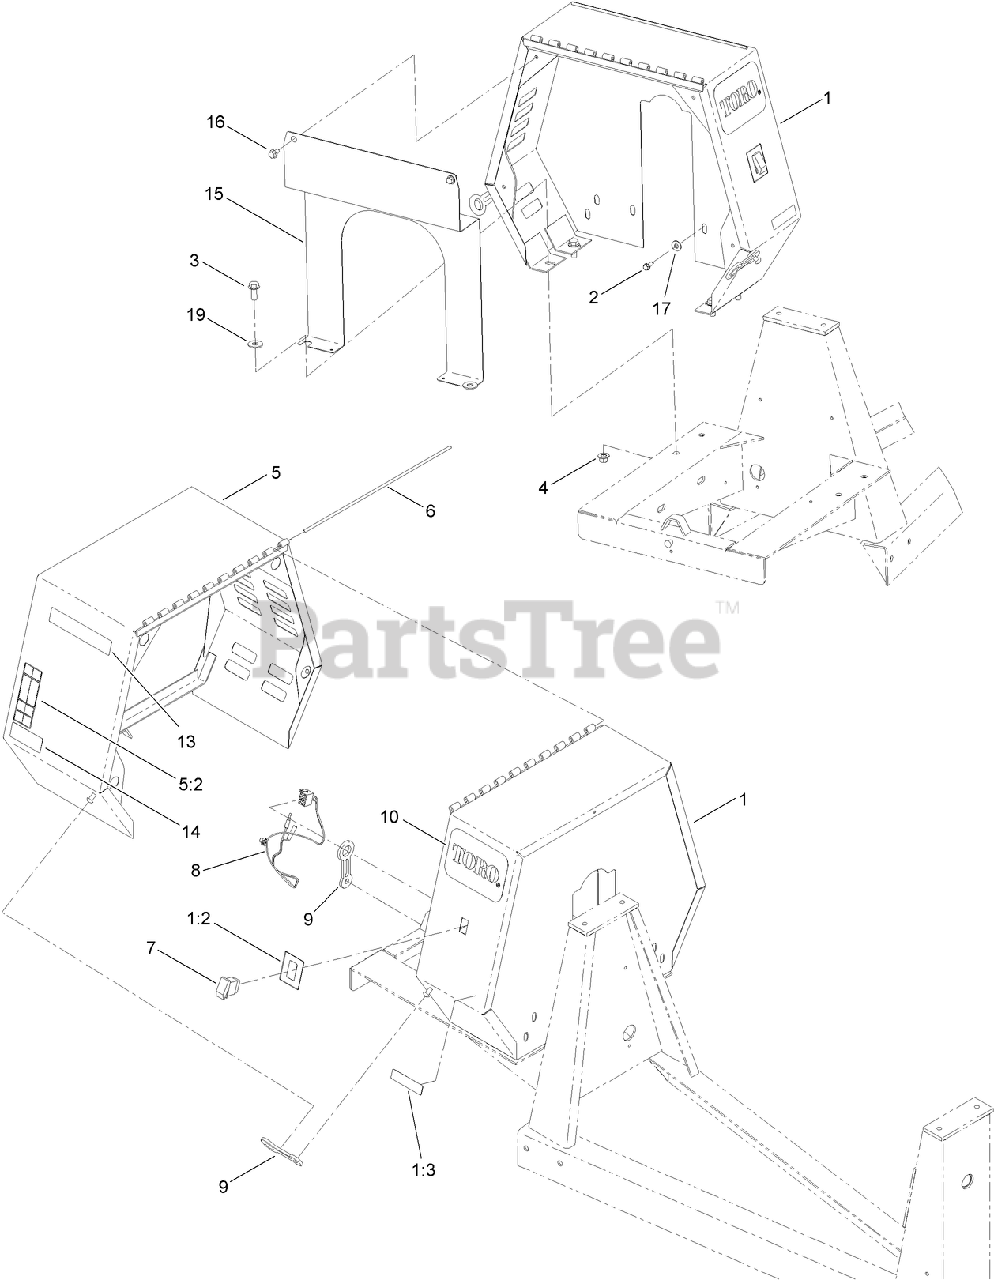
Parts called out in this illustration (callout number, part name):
1	STATIONARY COWL ASM
1:2	DECAL-STOP, ENGINE
1:3	DECAL-ARRESTER, SPARK
2	SCREW-HWHTF
3	SCREW-HHF
4	NUT-LOCK
5	MOVABLE COWL ASM
5:2	DECAL-WARNING
7	SWITCH
8	HARNESS-WIRE, MIXER
9	LATCH-RUBBER
10	DECAL
15	PLATE-ENGINE
16	SCREW-HWH
17	WASHER-FLAT
19	WASHER-FLAT
